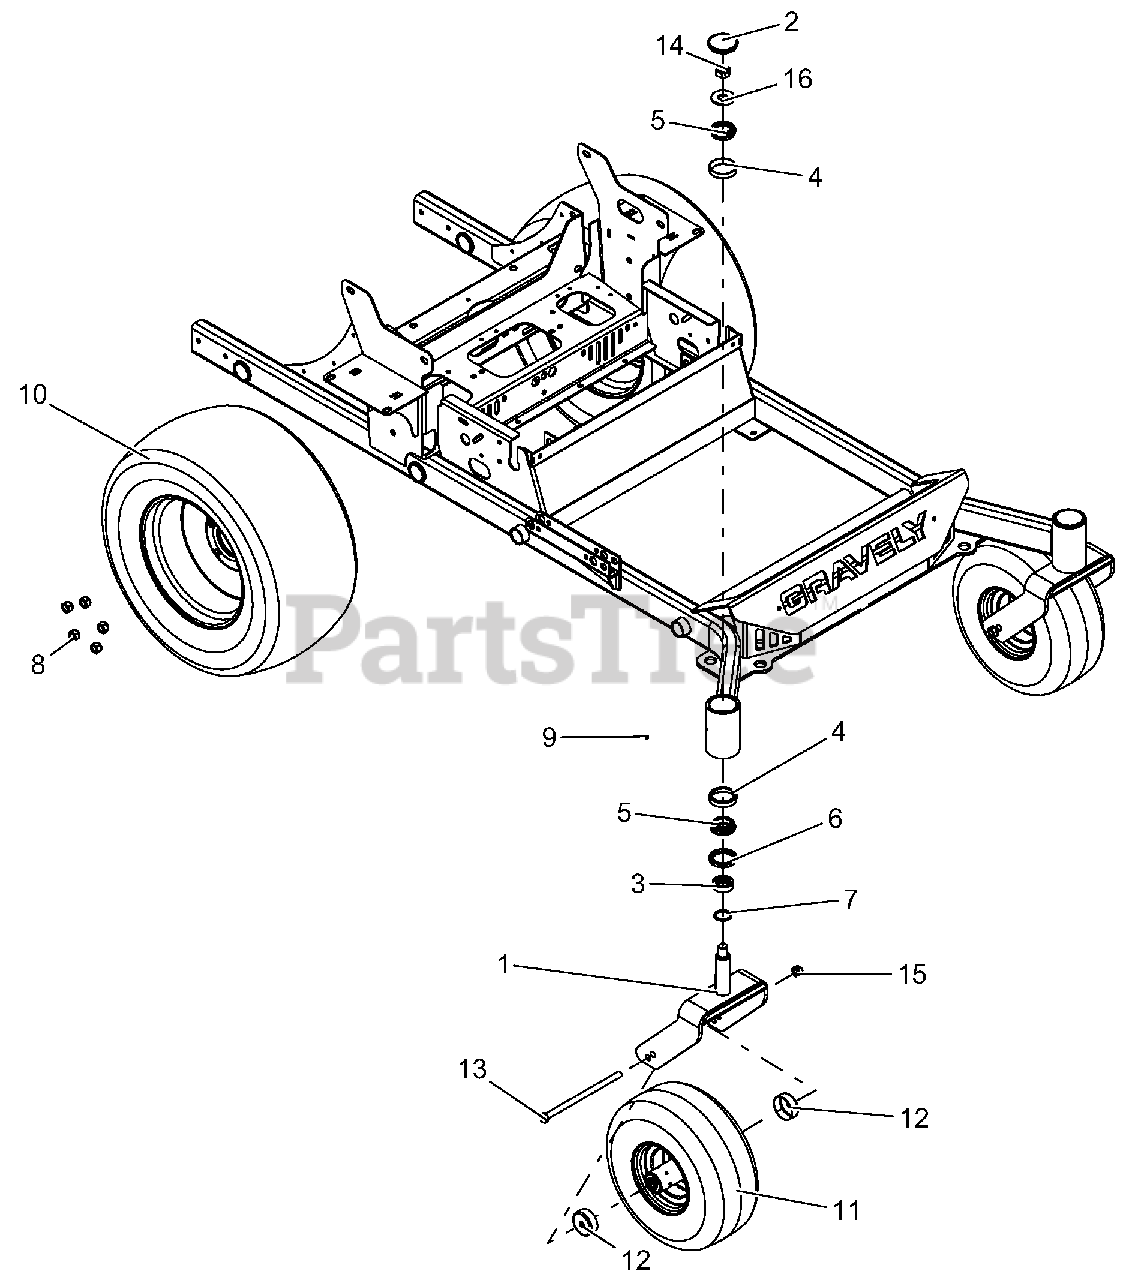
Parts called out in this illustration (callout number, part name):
1	WMT, CASTER FORK - RED
2	CAP, DUST
3	SPCR, FRONT CASTER FORK
4	BRG, CUP 2.328X.465
5	BRG, CONE 1.25 X6 .6
6	SEAL, OIL 1.75 X 2.332 X .312
7	O-RING, .139 W X 1.234 ID
8	NUT, LUG .500-13
9	PLUG, .250-28 X .185 HEX HEAD
10	ASSM TIREWHEEL, 24X11.50-12
11	TIRE/WHEEL, 15 X 6.00-6 SEMI-PNEU
12	SHIELD, WHEEL BEARING
13	BLT-HEX .50-13X9.00 GR5 YWZC
14	@NUT-LK-CTR-JAM .75-16 YWZC
15	NUT, LK-TOP-FLG .50-13 YWZC
16	WSHR-FL-STL.812X2.00X.148YWZC
